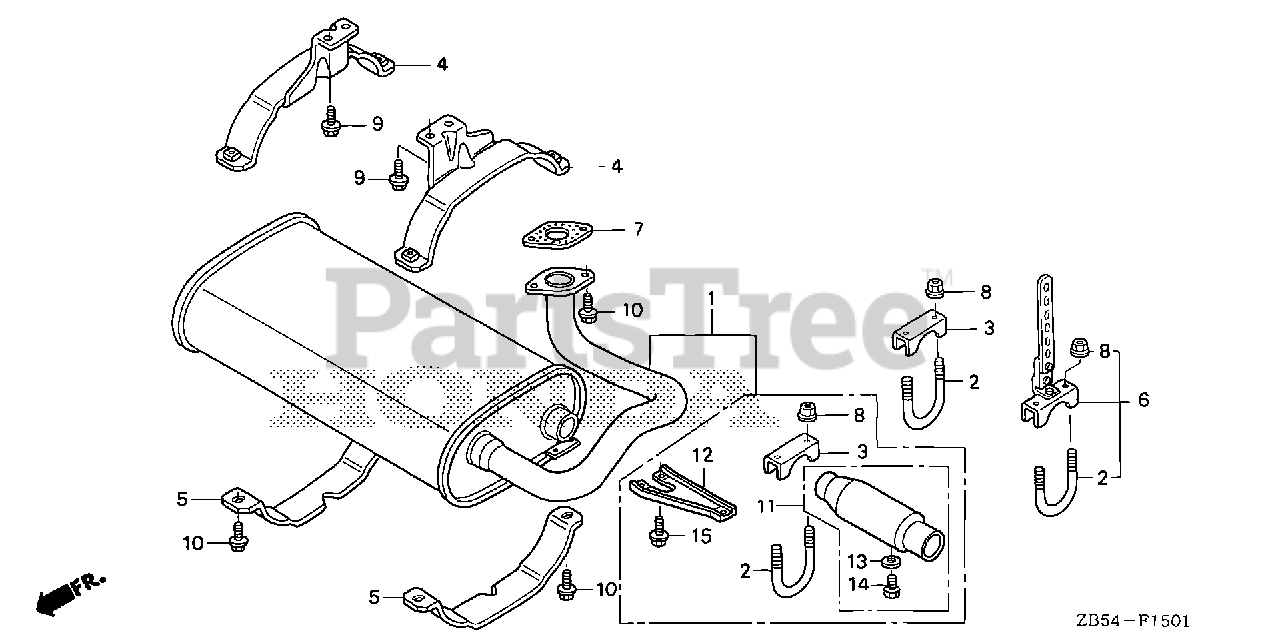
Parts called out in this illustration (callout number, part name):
2	BOLT, MUFFLER TAIL PIPE
3	CLAMP, MUFFLER TAIL PIPE
4	STAY, MUFFLER
5	SUPPORT, MUFFLER
6	BRACKET ASSY., MUFFLER TAIL PIPE
7	GASKET, MUFFLER
8	NUT, FLANGE (8MM)
9	BOLT, FLANGE (8X16) Use from Engine SN 1000016.
10	BOLT, FLANGE (8X20) Use up to Engine SN 1609606.
11	ARRESTER, SPARK
12	BRACKET A, MUFFLER
13	WASHER, PLAIN (10MM)
14	BOLT, HEX. (10X12)
15	BOLT, FLANGE (6X12) Use up to Engine SN 1543277.
